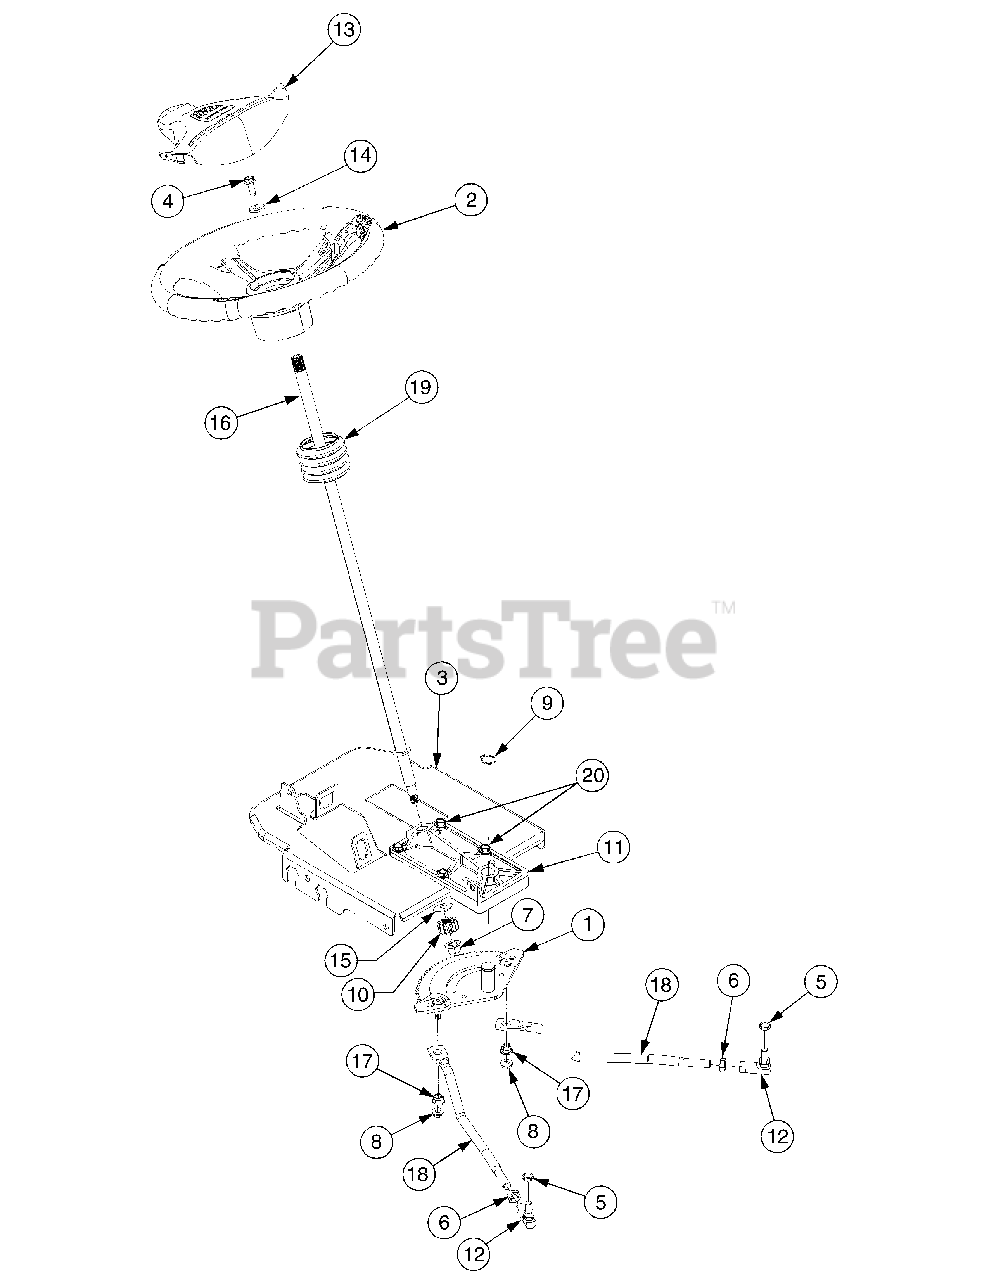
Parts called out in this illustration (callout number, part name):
1	Gear Assy, Segment
2	Wheel, Steering, Soft Grip
4	Screw, Hx. Wash. Hd Tapp, 5/16-18 x .875
5	Nut,Hex Center Lock, 3/8-24 GrB
5	Nut, Hex Jam Lock, 3/8-24 Gr2
6	Nut, Hex Jam, 7/16-20 GR2
7	Nut, Flange Lock 7/16-20 GrB
8	Nut, Hex Flange Lock, 5/16-18 GR5
9	Ring, Snap, .75 Dia Shaft
10	Gear, Steering Pinion
11	Housing Assy, Steering
12	Joint, Ball, 3/8-24
13	Cover, Steering Wheel
14	Washer, Flat, .406 x .875 x .105 Thk
15	Washer, Flat, .51 x 1.12 x .03 Thk
16	Shaft, Steering, .625 x 27.10
17	Plastic Bushing, .38 ID
18	Link, Drag
19	Bellow, Steering, 2.12 Lg
20	Screw, Hx. Wash. Hd Tapp, 5/16-18 x .75
20	Screw, Hx. Wash. Hd Tapp, 5/16-18 x 1.0
